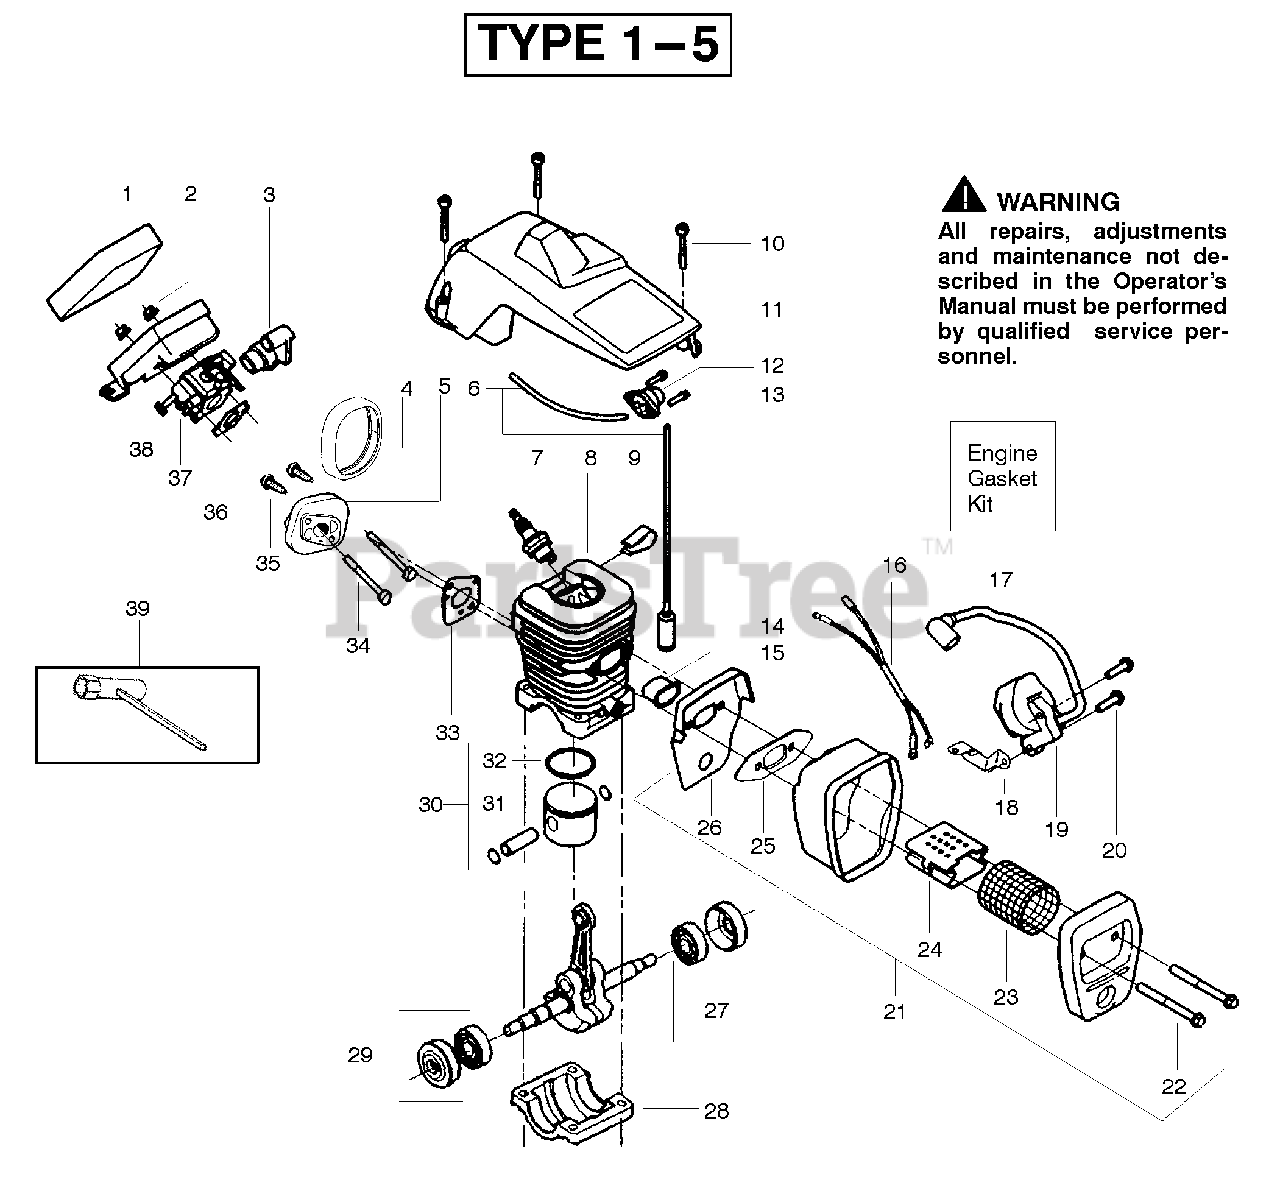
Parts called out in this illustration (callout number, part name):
1	Foam- Air Filter
3	Grommet-Carb Adjust
4	Seal-Carb Adapter
5	Carb. Adapter
6	Fuel Line Kit (Small)
7	Spark Plug (RCJ-7Y)
8	Kit-Cylinder
9	Clip-High Tension Lead
11	Cylinder Shield
12	Air Purge Ass'y.
14	Fuel Pick-up Ass'y.
15	Heat Insulator
16	Assy. -Wire Harness
17	Kit-Engine Gasket
18	Strap-Ground
19	Module- Ignition
21	Assy-Muffler
23	Screen-Spark
24	Diffuser-Muffler
25	Gasket-Muffler (kit)
26	Backplate-Muffler
27	Assy. - Crankshaft
28	Cap-Crankcase
29	Assy.-Seal & Bearing
30	Kit-Piston
31	Retainer-Piston Pin
32	Ring - Piston
33	Gasket-Carb. Adap.(kit)
36	Gasket - Carb. (kit)
37	Kit-Carburetor (WT-324)
38	Housing- Air Filter
39	Wrench - Bar
